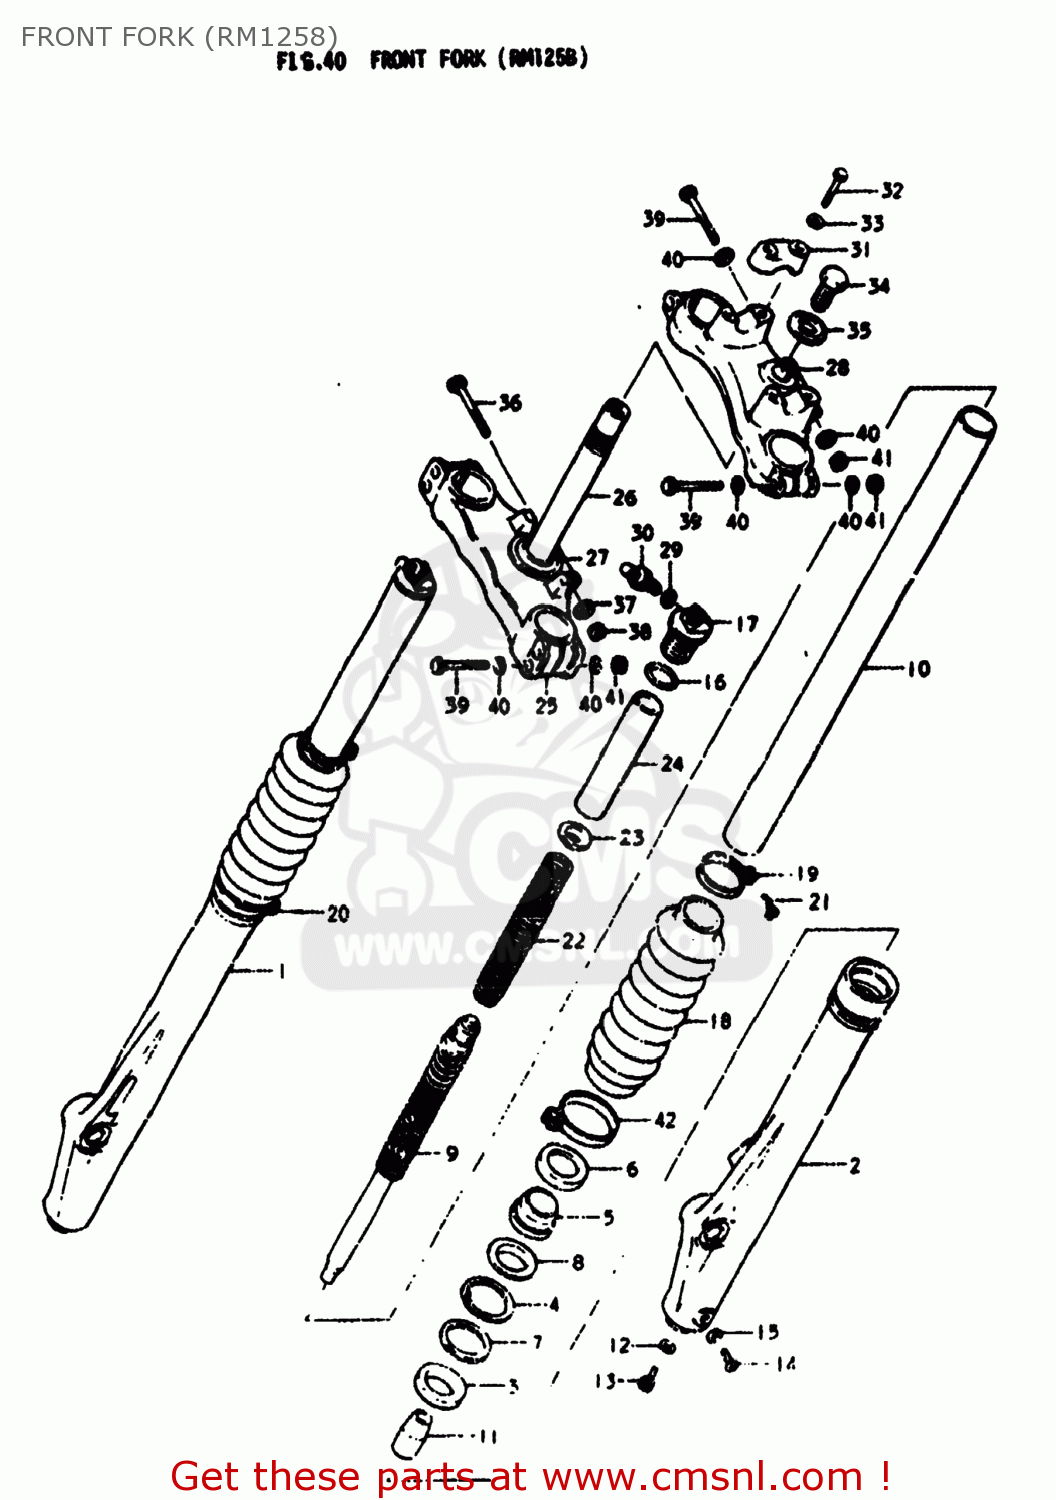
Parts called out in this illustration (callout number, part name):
1	TUBE,OUTER,RIGHT
2	TUBE,OUTER,LEFT
3	OIL SEAL,FRONT FORK
4	CIRCLIP,FORK OIL SEAL
5	DUST SEAL,FRONT FORK
6	GUIDE.FORK DUST
7	WASHER
8	LABEL
9	CYLINDER,FRONT FORK
10	TUBE,FORK,INNER
11	PIECE,OIL LOCK
12	GASKET (NAS)
13	BOLT
14	SCREW
15	GASKET,DRAIN,PLUG (NAS)
16	O RING
17	CAP
18	BOOT
19	BAND,BOOT
20	BAND,FRONT FORK COVER
21	SCREW
22	SPRING
23	GUIDE,FRONT FORK SPRING C
24	SPACER,FRONT FORK SPRING
25	STEM,STEERING
26	STEM,STEERING
27	RACE,STEERING OUTER LWR
28	HEAD,STEERING STEM
29	O RING
30	VALVE
31	HOLDER,HANDLEBAR
32	Bolt
33	LOCK WASHER
34	BOLT,STEERING STEM HEAD
35	WASHER
36	BOLT
37	LOCK WASHER
38	NUT
39	BOLT
40	WASHER
41	NUT
42	BAND,FRONT FORK COVER
